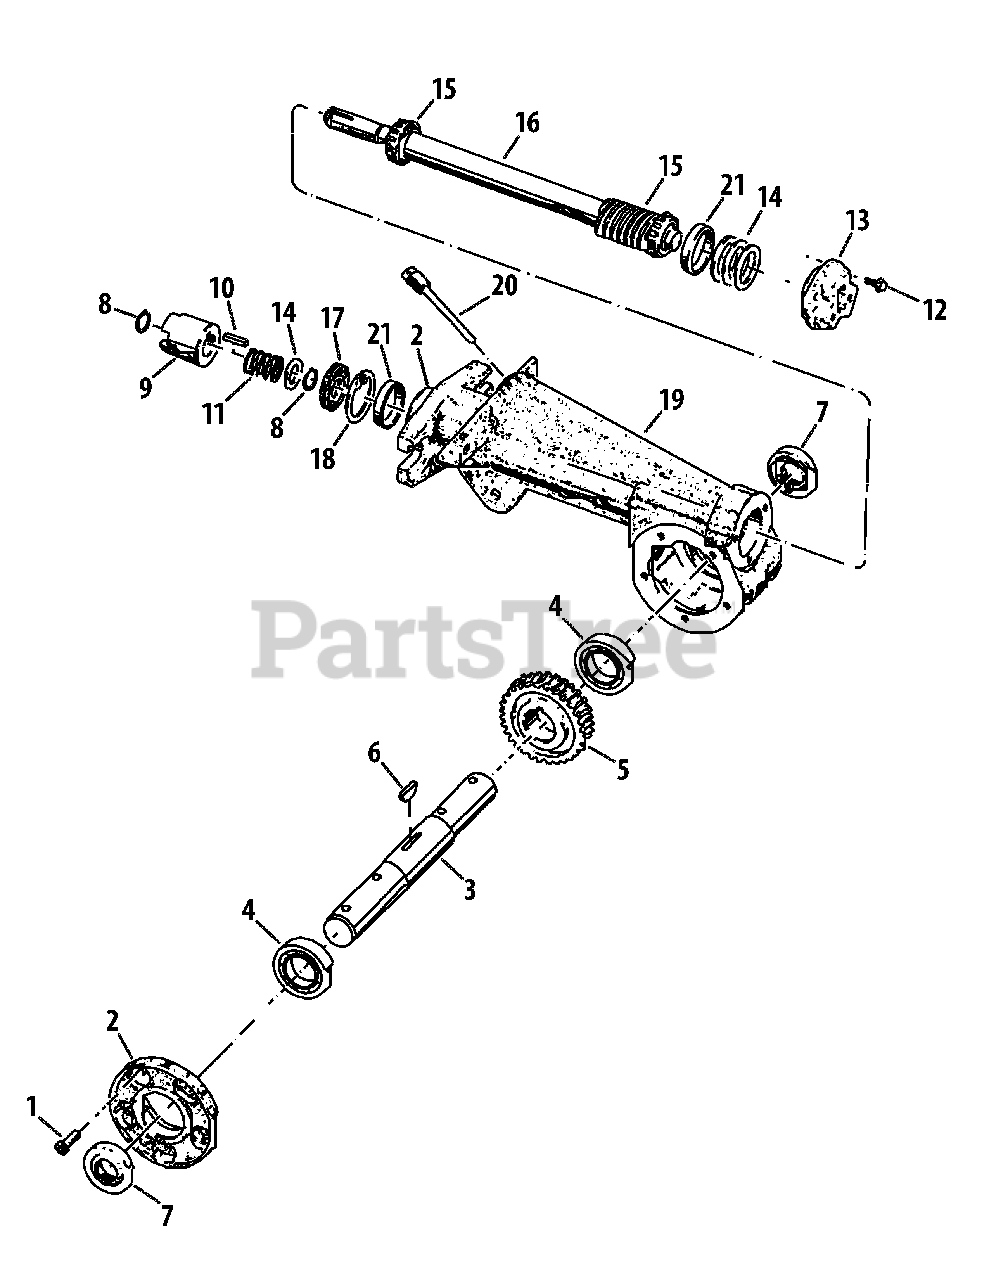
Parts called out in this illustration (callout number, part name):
1	Self-Sealing Screw, 1/4"-20 x 5/8"
2	Tiller Housing Cover
3	Tine Shaft
4	Ball Bearing
5	Worm Gear
6	Woodruff Key
8	External Retaining Ring
9	Dog Clutch
10	Key, 3/16" x 1"
12	Self-Sealing Screw, 1/4"-20 x 7/8"
14	Flat Washer, 1.75 x 1.5 x .062
14	Flat Washer, 1.75 x 1.5 x .005
14	Flat Washer, 1.75 x 1.5 x .03
14	Flat Washer, 1.75 x 1.5 x .01
15	Cup Bearing
18	Retaining Ring
19	Attachment Housing
20	Oil Dipstick
21	Cone Bearing
